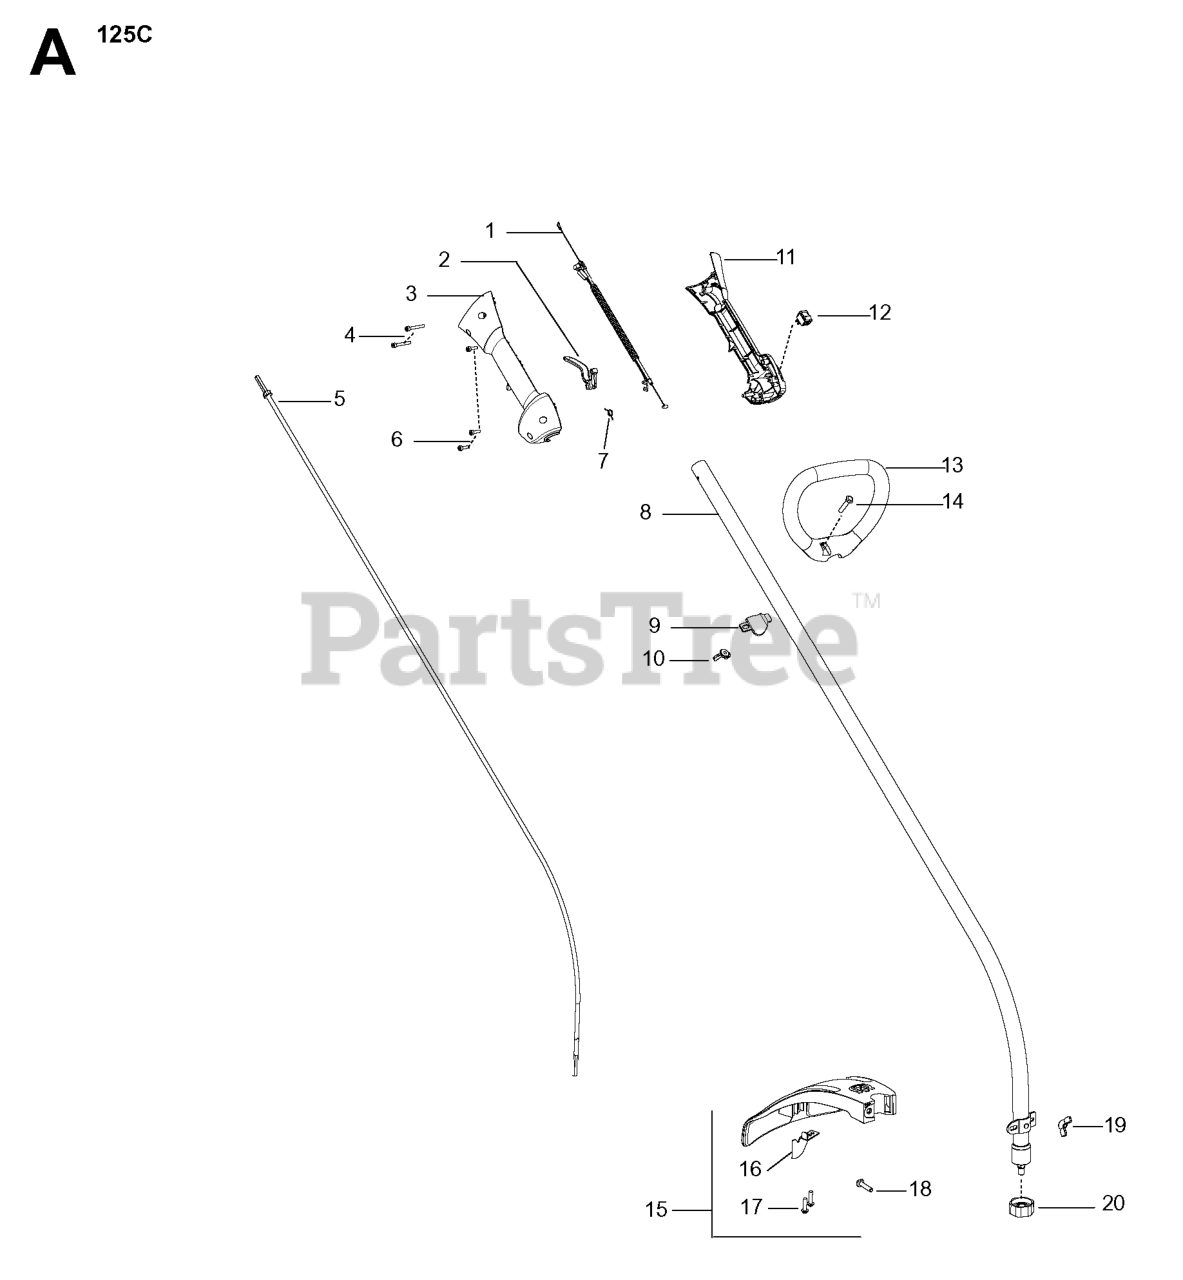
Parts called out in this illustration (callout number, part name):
1	%ASSY CABLE WIRE HARNESS
2	TRIGGER
3	HSG THROTTLE RH W/O SLOT
5	FLEX SHAFT 52"
6	SCREW M4 X 1.75 PT 16MM
7	SPRING TRIGGER
8	KIT DRIVESHAFT
9	CLAMP ASSIST HANDLE
10	WINGNUT, TYPE 2
11	THROTTLE HSG LH
12	KIT SWITCH
13	HANDLE ASSIST
14	BOLT, TYPE 2
15	TRIMMER GUARD 128C
18	BOLT, TYPE 2
19	WINGNUT, TYPE 2
20	ASSY- DUST CUP"C UNIT"
